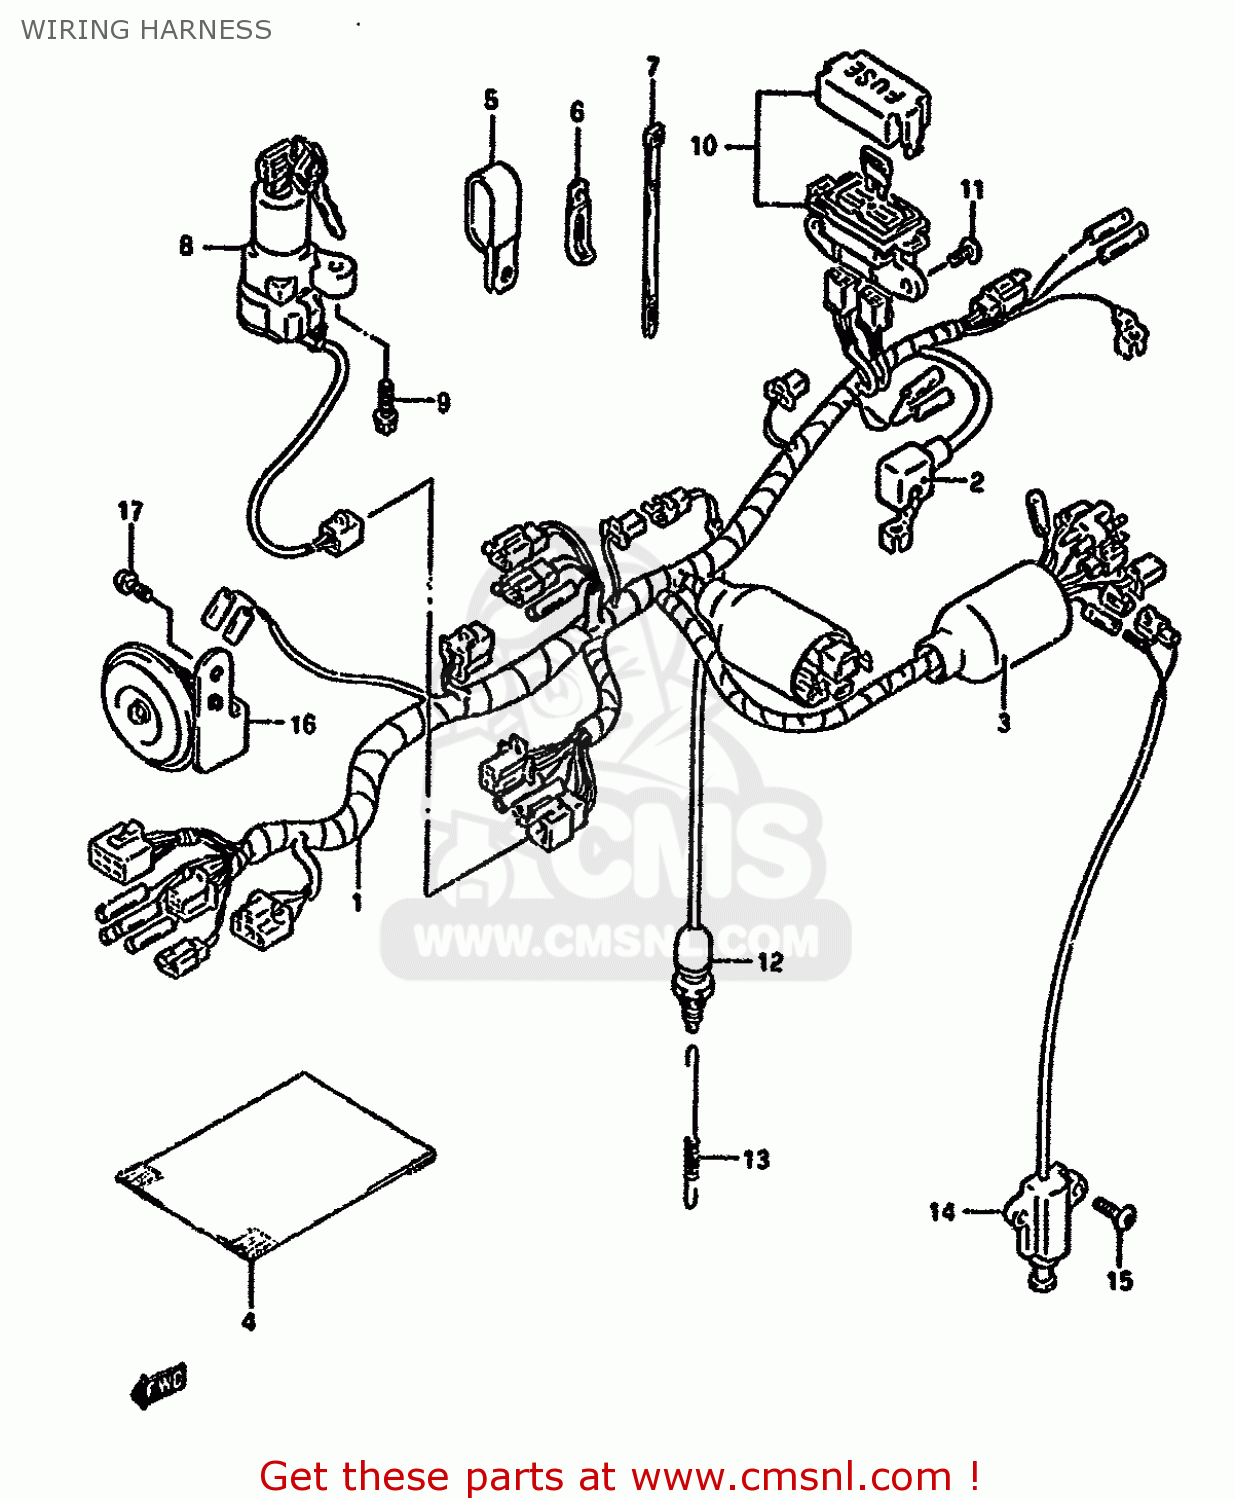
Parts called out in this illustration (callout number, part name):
1	HARNESS,WIRING
2	CAP,BATTERY TERMINAL
3	BOOT,WIRING HARNESS
4	BOOT,WIRING HARNESS
5	CLAMP
6	CLAMP
7	CLAMP(L:120)
8	LOCK ASSEMBLY,STEERING
9	SCREW(6X18)
10	BOX ASSEMBLY,FUSE
11	SCREW
12	SWITCH ASSY,STOP LAMP
13	SPRING
14	SWITCH ASSEMBLY,SIDE STAND
15	SCREW, 6X20
16	HORN ASSEMBLY
17	BOLT
